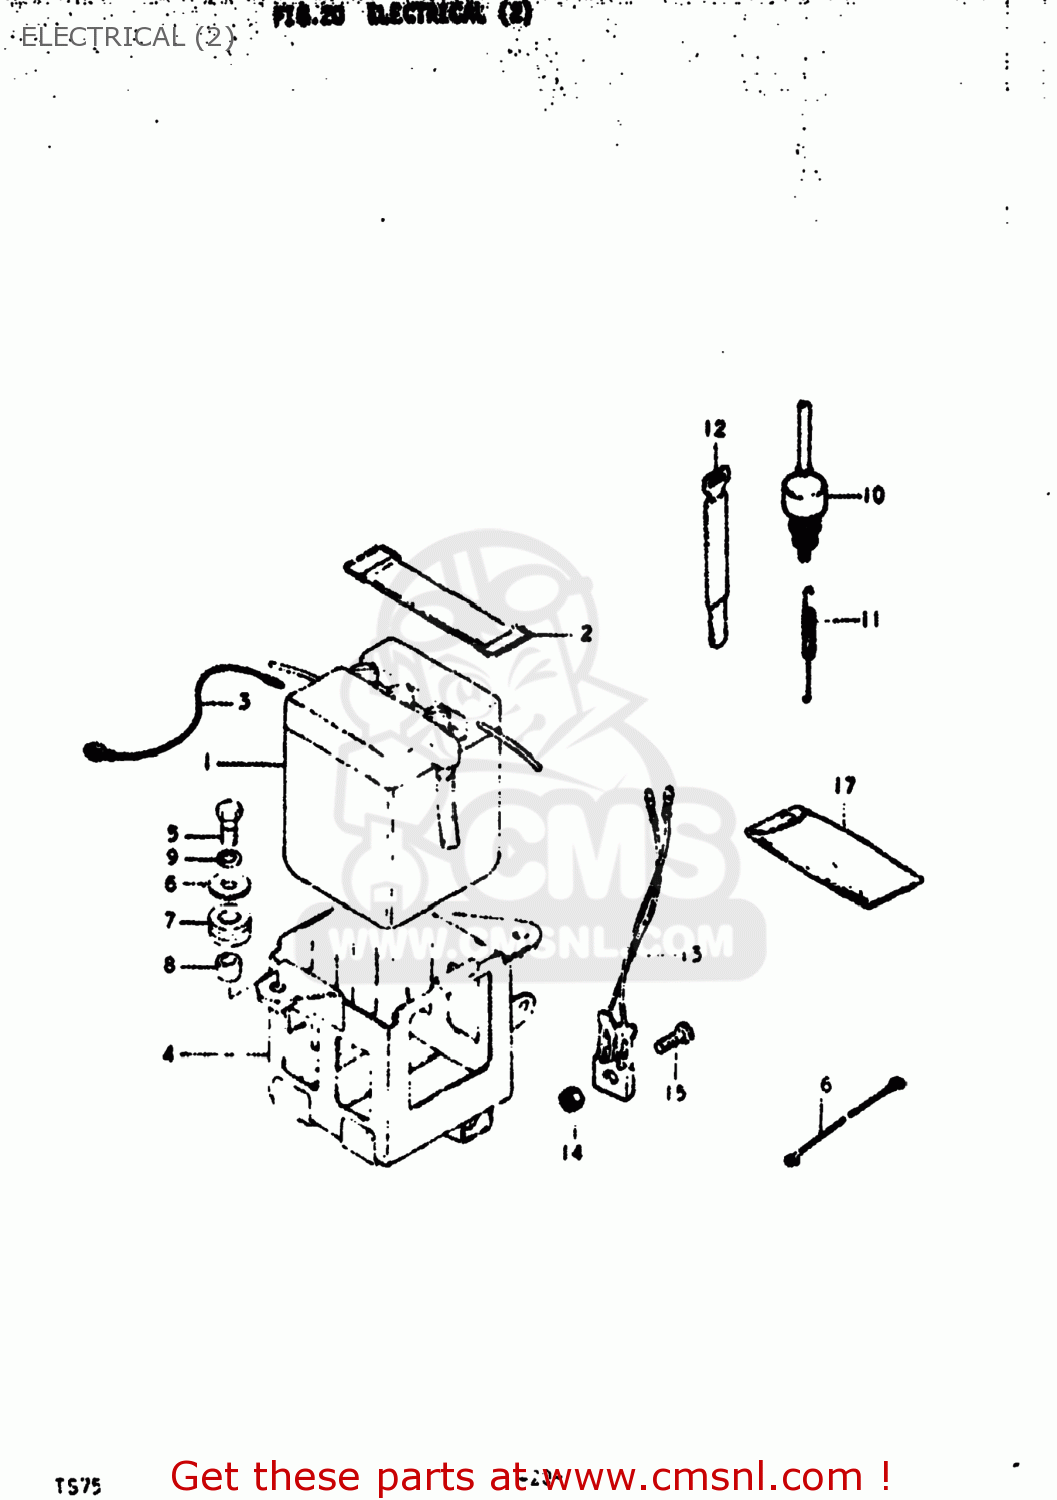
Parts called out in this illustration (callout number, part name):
1	BATTERY ASSY(6N4-2A4.2AH)
2	BAND
3	LEAD WIRE
4	HOLDER,BATTERY
5	BOLT
6	WASHER (6.5X20X1.2)
7	CUSHION
8	SPACER (7X9X7)
9	LOCK WASHER
10	SWITCH,BRAKE LAMP
11	SPRING
12	CLAMP
13	RECTIFIER ASSEMBLY
14	NUT
15	SCREW
16	WIRE
17	TOOL SET
